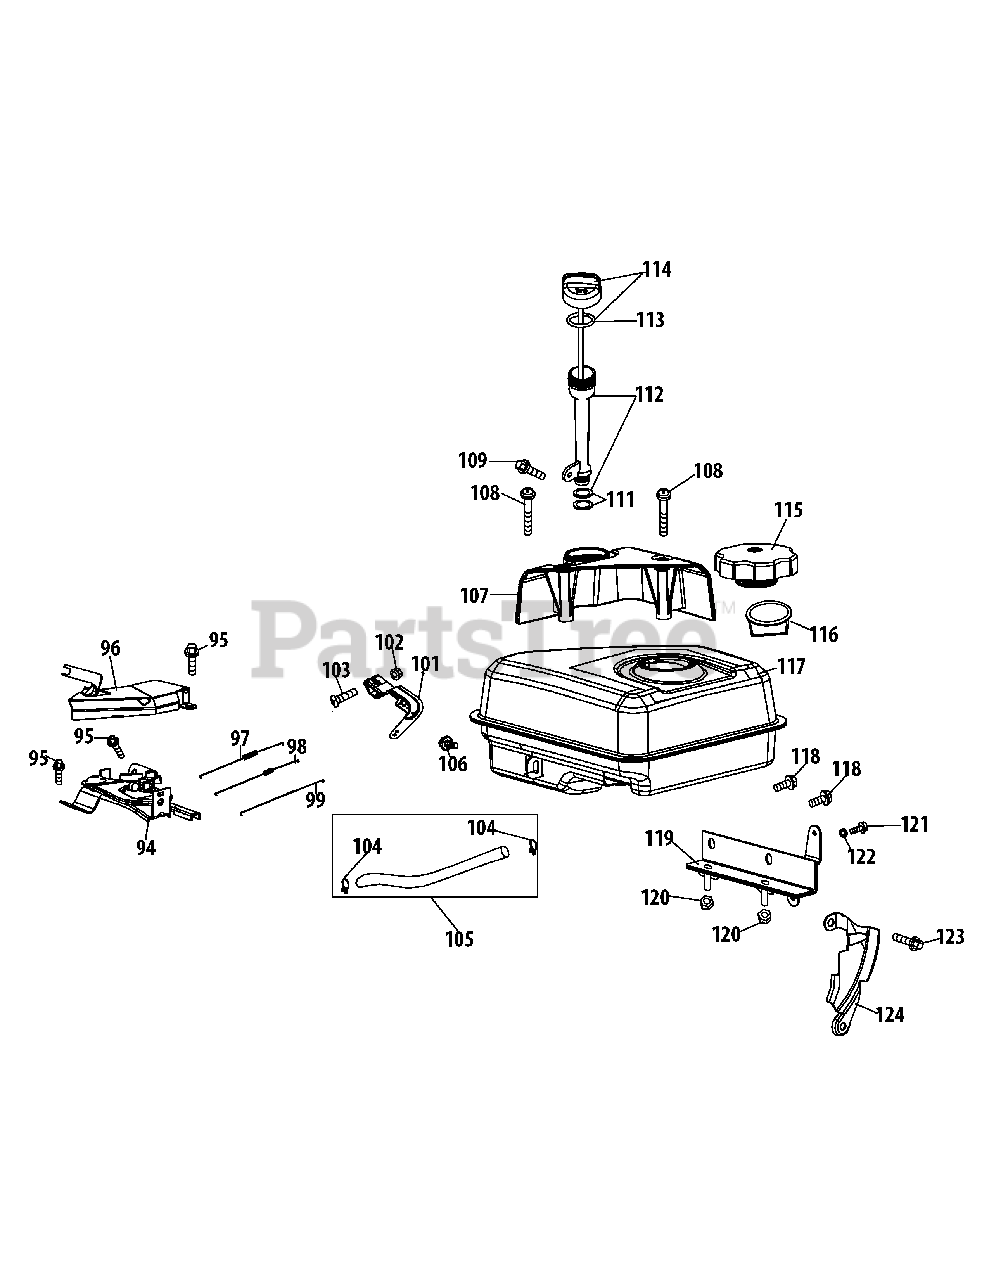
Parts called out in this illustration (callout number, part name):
94	Primer Bracket
95	Bolt M6×12
96	Governor System Shield
97	Governor Spring
98	Throttle Linkage Spring
99	Throttle Linkage
101	Governor Arm
102	Nut M6
103	Governor Arm Bolt
104	Fuel Hose Clamp
105	Fuel Hose
106	Bolt M6×12
107	Dipstick Decoration Cover
109	Bolt M6×12
111	Oil Fill Tube O-Ring
112	Oil Fill Tube Assembly
113	Dipstick O-Ring
114	Dipstick Assembly
115	Fuel Cap Assembly
116	Fuel Level Indicator
117	Fuel Tank Assembly
118	Bolt M6×10
119	Switch Housing Mounting Bracket
120	Nut, M6
121	Bolt M4×10
122	Washer 4
123	Bolt M6×20
124	Blower Housing Shield
